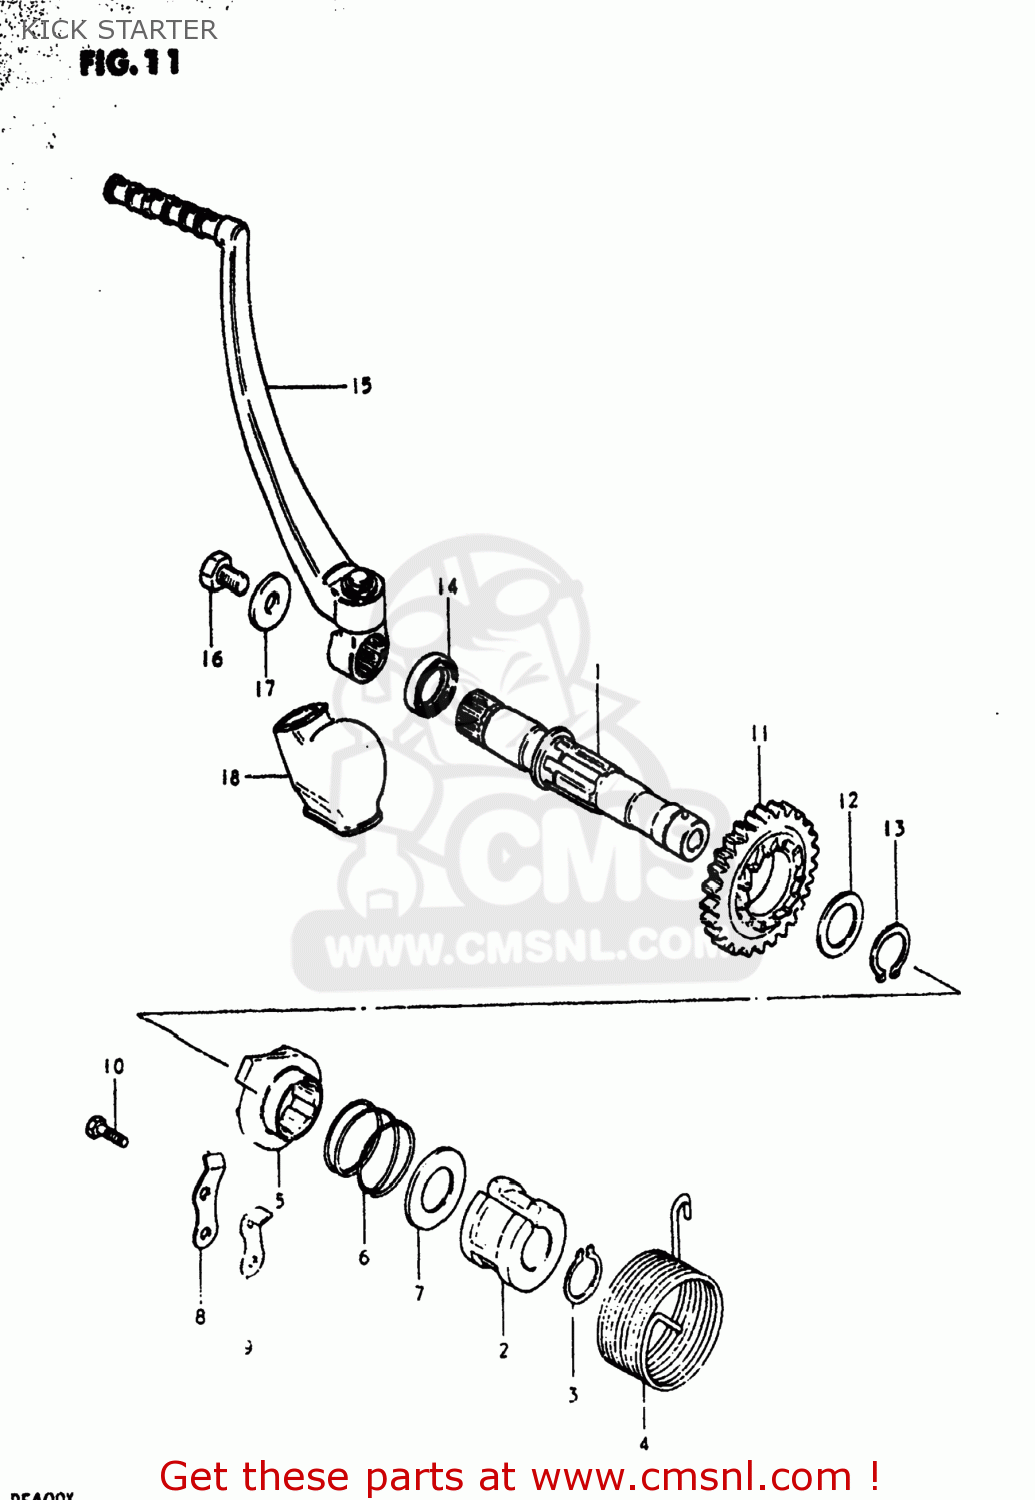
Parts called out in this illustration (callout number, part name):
1	SHAFT,KICK STARTER
2	GUIDE,KICK STARTER SFT SPRING
3	CIRCLIP
4	SPRING
5	STARTER,KICK
6	SPRING
7	WASHER
8	GUIDE,KICK STARTER
9	STOPPER,KICK STARTER
10	BOLT(8X20)
11	GEAR,KICK STARTER DRIVE
12	SHIM
13	CIRCLIP
14	SEAL,OIL(20X27X5)
15	LEVER ASSEMBLY,KICK STARTER
16	BOLT
17	WASHER(8.2X23X3.2)
18	COVER,KICK LEVER JOINT
